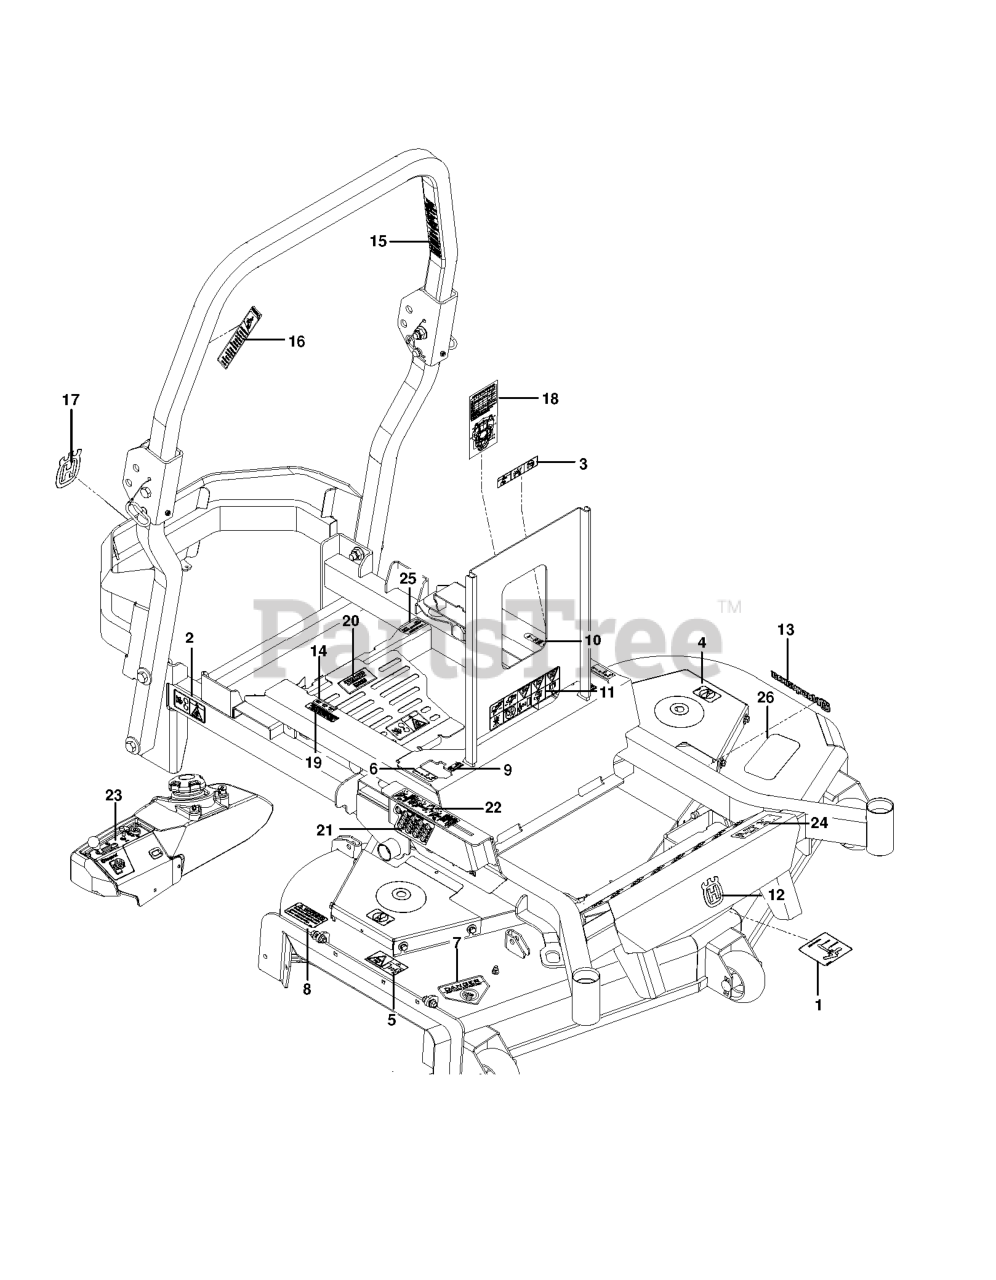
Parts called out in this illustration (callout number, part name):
1	DECAL, BELT ROUTING
2	DECAL, BELT DRIVE
3	EURO DECAL-BATTERY WARNIN6
4	DECAL, NO STEP
5	DECAL, EURO SEVERING
6	DECAL, MOTION CONTROL
7	DECAL, CPSC
8	DECAL, CAUTION
9	DECAL, F.S.T.
10	DECAL, PARK BRAKE
11	DECAL, WARNING
12	DECAL.AUGER.HUSQ.CROWN.SNOW
13	RP.DECAL.BADGE.170MM.TEXTLOGO
14	DECAL, FUSE
15	DECAL, ROPS
16	DECAL, ROPS, WARNING
17	DECAL, CROWN H, 110MM
18	DECAL, SERVICE
19	DECAL, WARNING SPARK ARRESTOR
20	HG_DECAL, ZT-3400
21	DECAL, HEIGHT
22	DECAL, RELEASE LEVER
23	DECAL, CONTROL, GAS
24	DECAL.P-ZT.54
25	DECAL, FUEL
